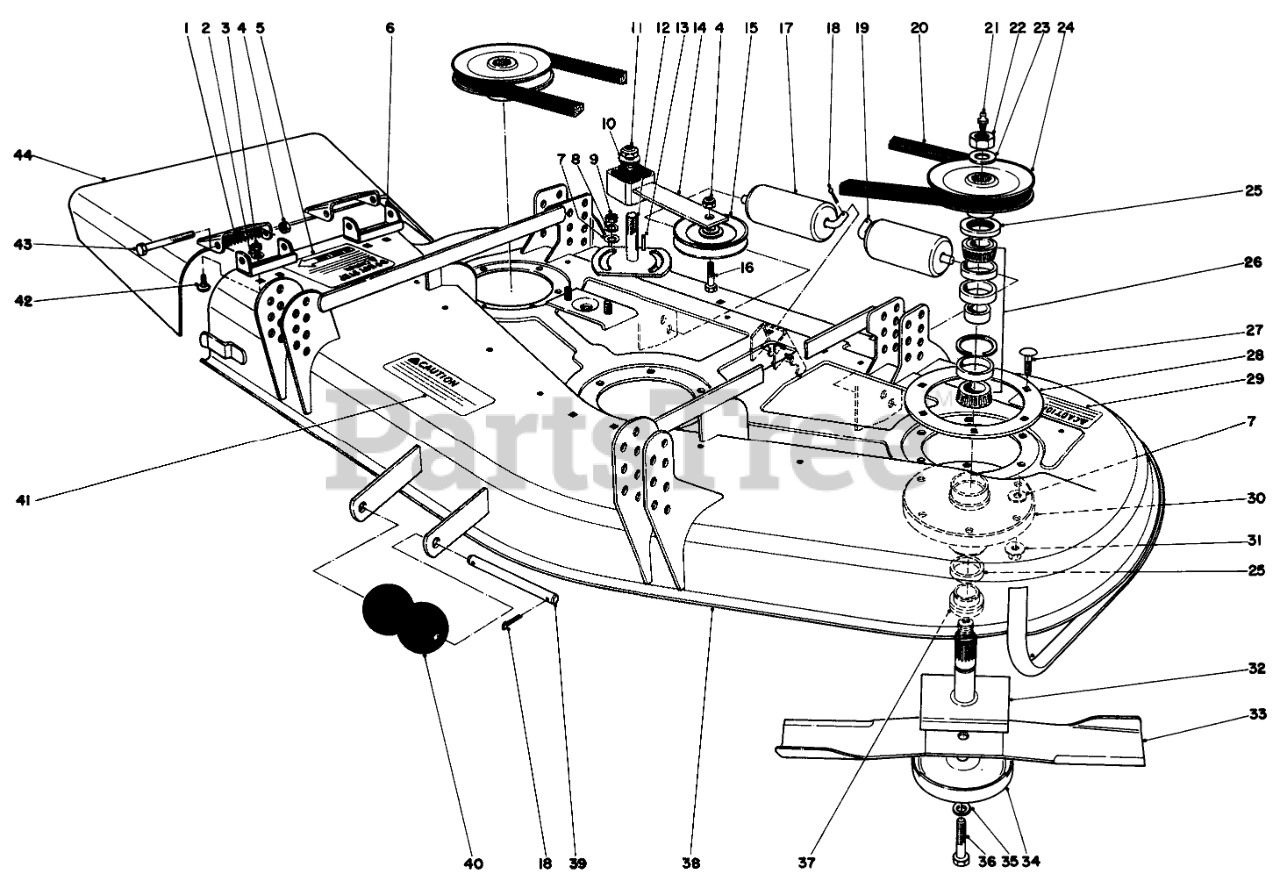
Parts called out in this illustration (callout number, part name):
1	SPRING
2	WASHER-LOCK
3	NUT-HEX
4	NUT-HEX
5	Decal-Caution
6	Bracket-Pivot
7	WASHER-FLAT
8	WASHER-LOCK
9	NUT-JAM
10	WASHER-FLAT
11	NUT-LOCK, NI
12	PLATE-IDLER
13	KEY-SQUARE
14	IDLER ARM ASM
15	Idler Pulley
16	SCREW-HH
17	ROLLER-DECK
18	PIN-COTTER
19	SHAFT-ROLLER, REAR
20	V-BELT
21	FITTING-GREASE
22	NUT-HEX
23	WASHER
24	PULLEY AND HUB ASM
25	SEAL-OIL
26	BEARING ASM
27	SCREW-CARR
28	SUPPORT-DECK, RING
29	DECAL-CAUTION, BLADE
30	Housing-Spindle
31	NUT-HF
32	SHAFT
33	Blade
34	Cup-Scalp
35	WASHER-LOCK
36	SCREW-BLADE
37	SPACER
38	GM 52 DECK WA RO
39	SHAFT-ROLLER
40	ROLLER
41	Decal-Caution
42	SCREW-CARR
43	SCREW-HH
44	Deflector
